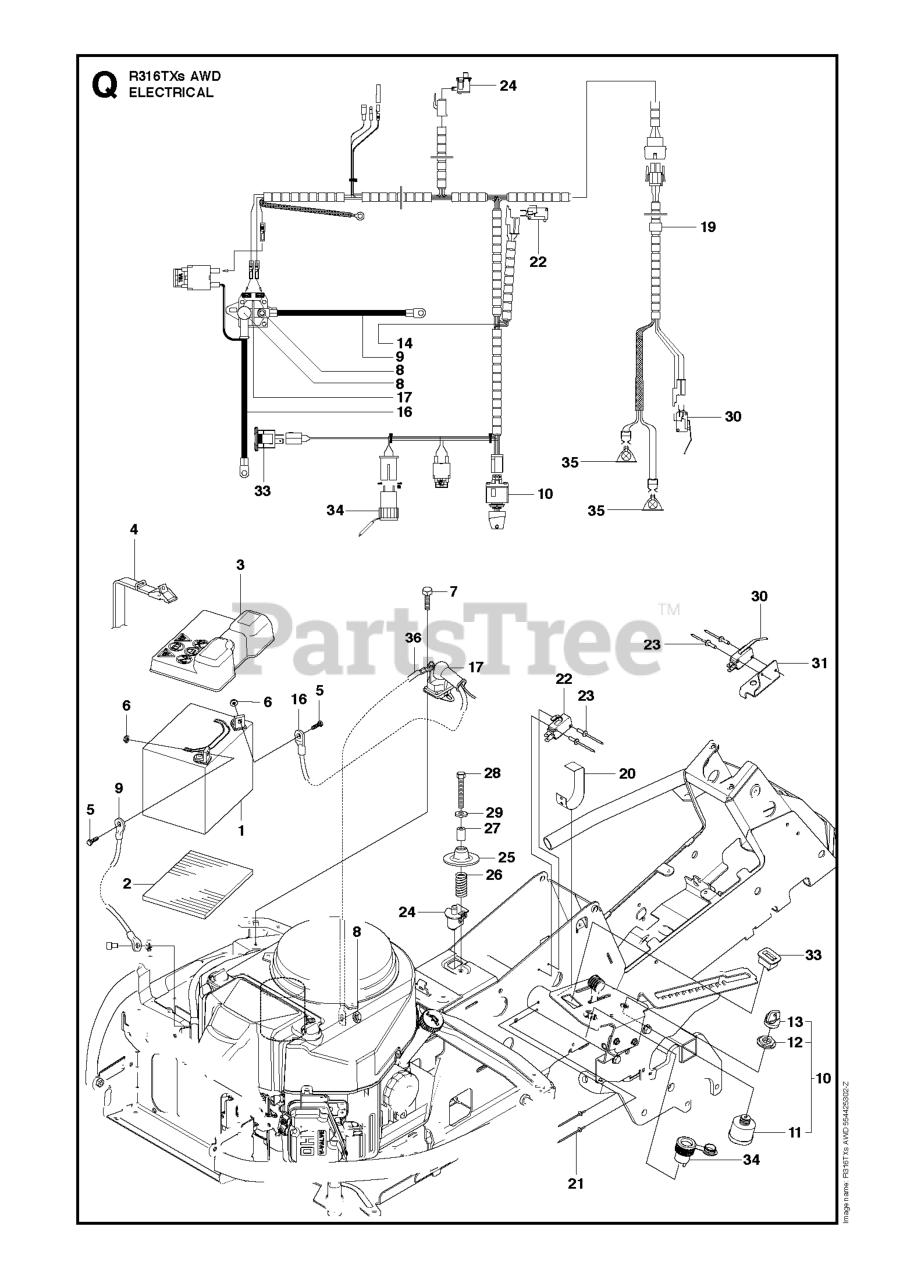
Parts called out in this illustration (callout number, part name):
5	SCREW EHHM
10	IGNITION SWITCH
11	IGNITION SWITCH
13	IGNITION KEY
16	CABLE
27	SPACER TUBE
28	SCREW
29	WASHER BRB 8.4X17
30	MICRO SWITCH
33	HOUR METER
